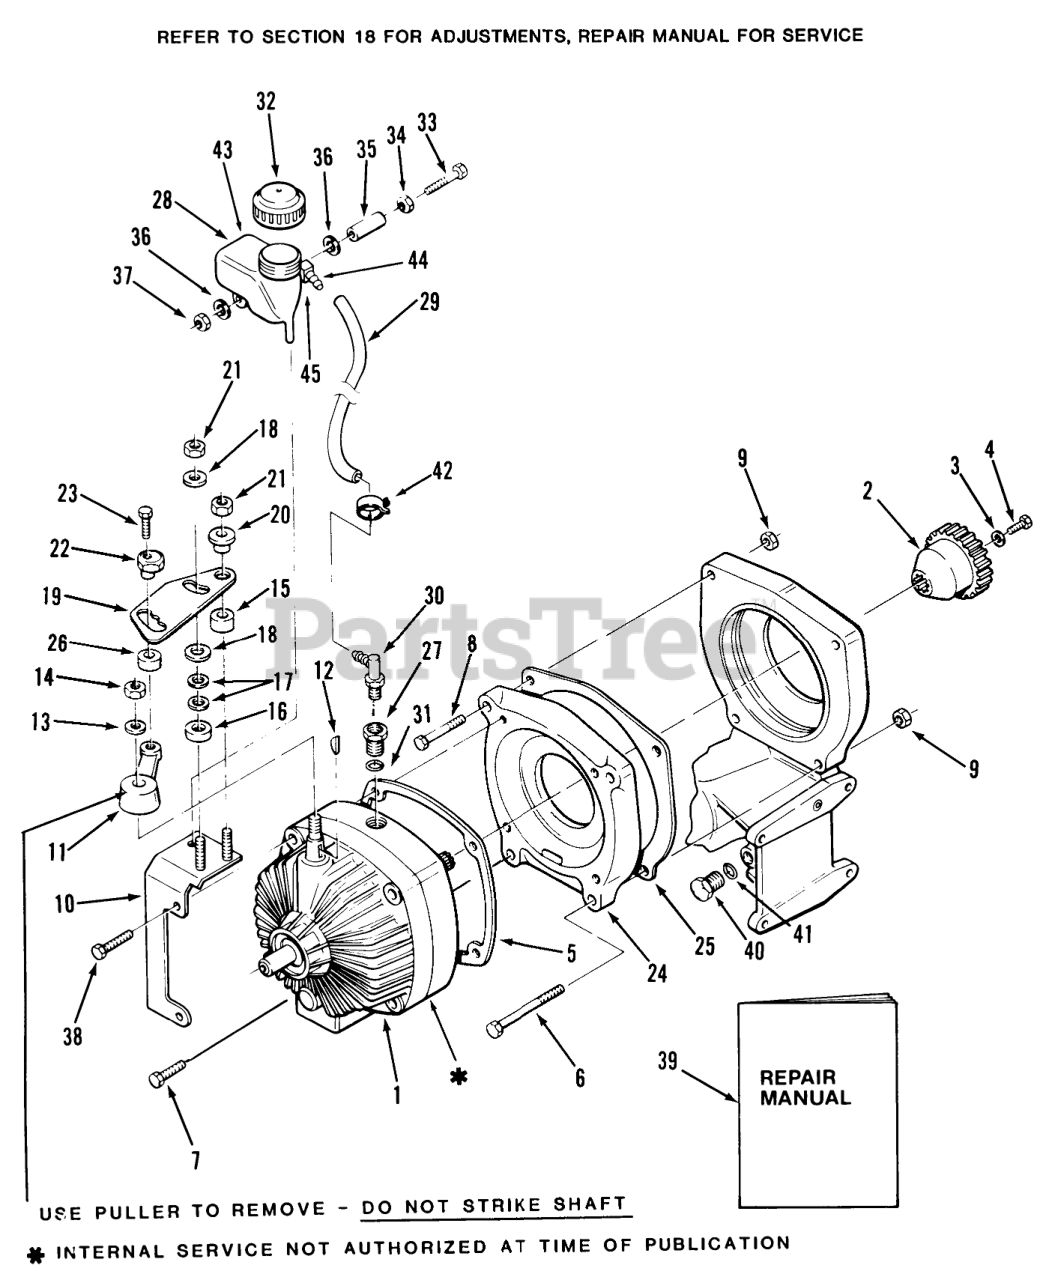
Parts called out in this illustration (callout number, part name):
1	TRANSMISSION HYDRO
2	GEAR 20TEETH DRIVE
3	WASHER
4	H H C S
5	GASKET HYDRO
6	H H C S
7	Bolt
8	BOLT SH 3/8-16X3 1/2
9	Nut
10	CONTROL SUPPORT ASSY R
11	ARM SPEED CONTROL
12	KEY WOODR 1/8X1/2 DI
13	Washer
14	Eslok Nut 3/8-16
15	SPACER-PIVOT
16	SPACER-FRICTION
17	WASHER-SPRING DISC
18	FRICTION WASHER
19	CAM-SPEED CONTROL (NS)
20	CAM-SPACER
23	Bolt
24	ADAPTER-HYDRO
25	GASKET
26	SPACER CAM
27	Plug Fitting w/O-ring
28	ASSY RESERVOIR TANK
29	Hose
30	FITTING-ELBOW
31	0-Ring
32	CAP VENTED B
33	BOLT 1/4-20 X 1 3/4
34	SPEED NUT
35	SPACER
37	Nut
38	Bolt
39	Repair Manual
40	PLUG-WITH O-RING
41	O-ring
42	Clamp
43	Reservoir Tank Only
44	FITTING
45	BUSHING
